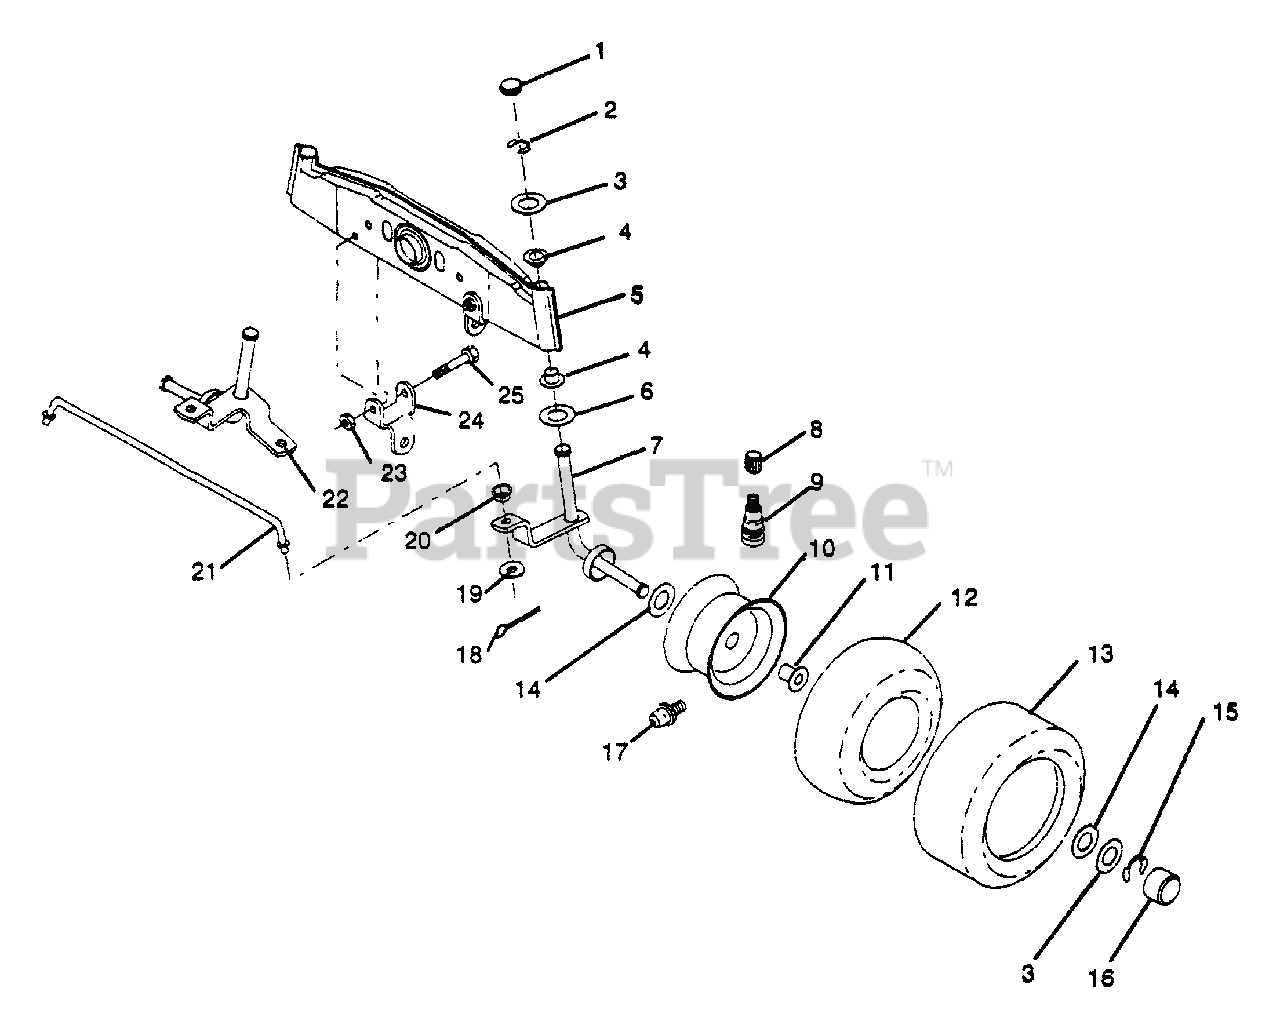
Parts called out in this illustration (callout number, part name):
1	Cap, Spindle
2	Ring, Clip
3	Washer 25/32 x 1-5/8 x 16 Ga.
5	Axle Front
6	Bearing, Thrust
7	Spindle R.H. Asm.
8	Cap, Valve
9	Stem, Valve
10	Rim
11	Bearing, Flange
13	Tire, Front
14	Washer 25/32 x 1-1/4 x 16 Ga.
15	Ring, Clip
17	Fitting, Grease
18	Pin, Cotter 1/8 x 3/4
19	Washer 13/32 x 13/16 x 16 Ga.
22	Spindle, LH. Asm.
23	Nut, Crownlock 5/16-18
24	Bracket, Front Stabilizer Link
25	Bolt, Hex, Fin. 5/16-18 UNC x 2-1/2
